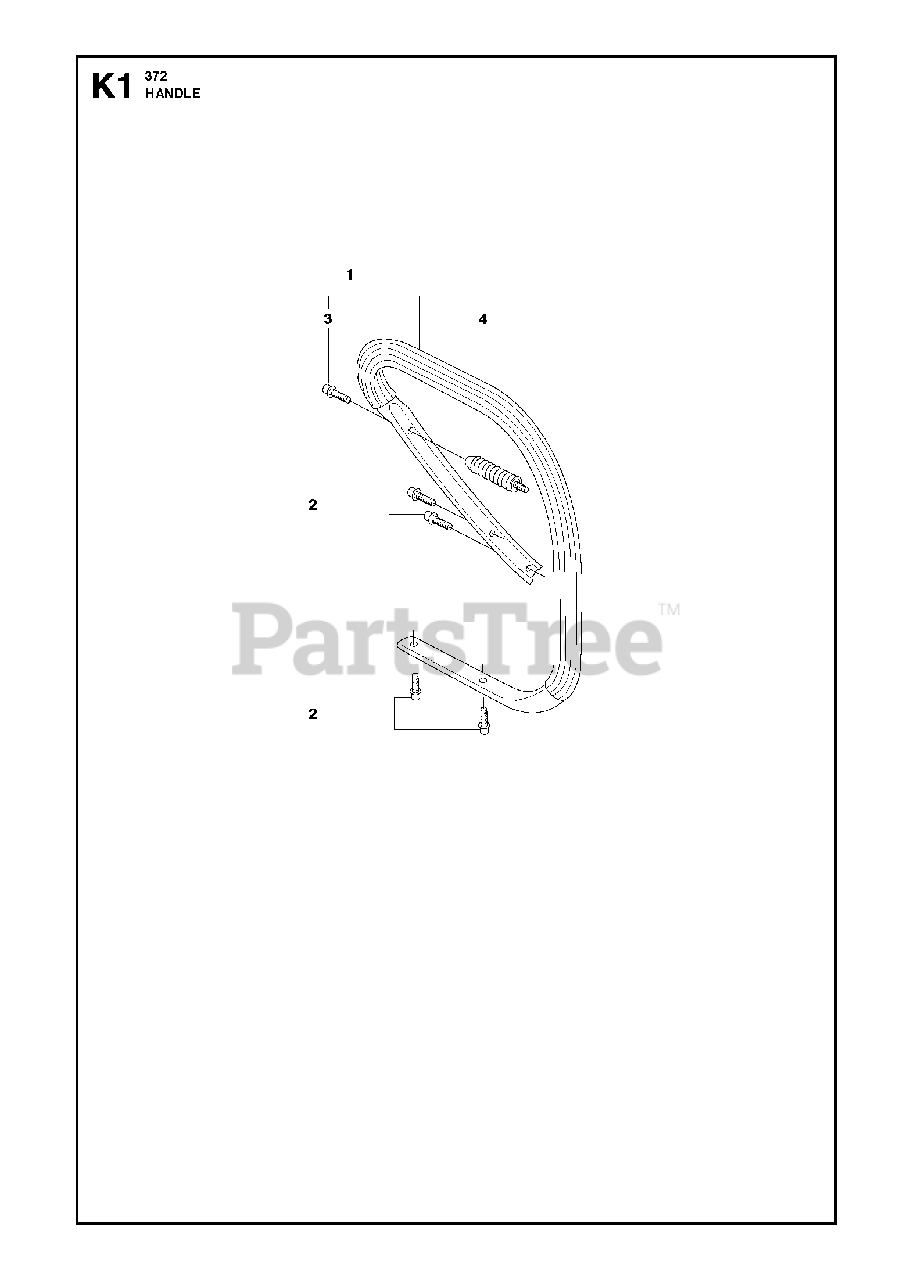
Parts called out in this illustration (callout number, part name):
1	FRONT HANDLE
2	SCREW
3	SCREW
4	ANTIVIBE MOUNT
4	VIBRATION ABSORBER
